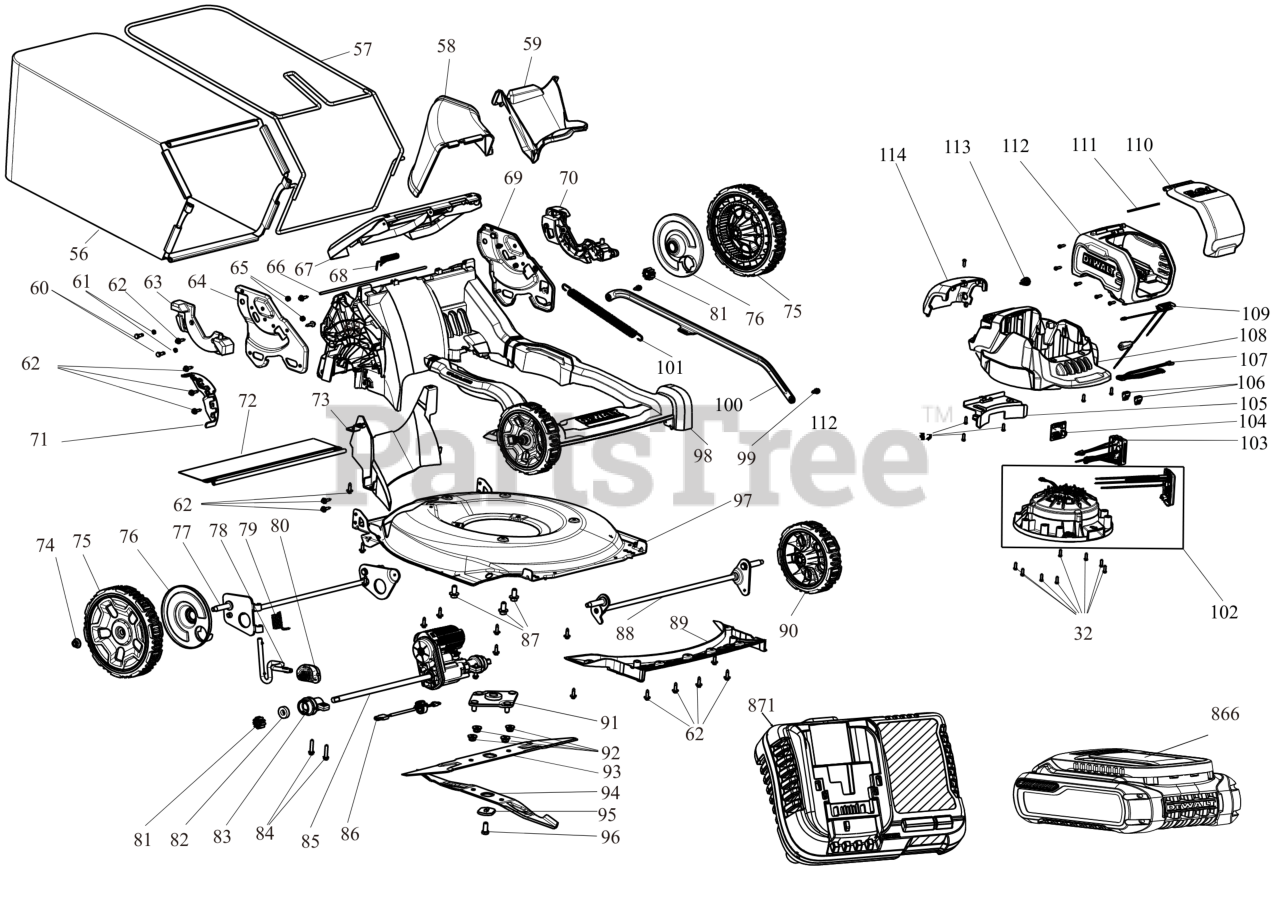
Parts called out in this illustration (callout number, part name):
1	BUTTON
2	SPRING
3	SCREW
5	COVER
6	POTENTIOMETER SA
7	CONTROL
9	BUTTOM
10	HANDLE
11	WIRE HARNESS
12	SWITCH
13	WIRE HARNESS
15	SCREW M6X45-T30-THD FRM
16	SWITCHBOX
18	HOUSING SA
19	CATCH
21	SPRING TORSION
22	WIRE HARNESS
23	PADDLE
24	PADDLE
25	PIVOT
26	COVER
27	STRIP
28	SLEEVE
29	TUBE UPPER
31	TUBE LOWER
32	SCREW M4.55X16 T20-PLAS THD FRM
33	SLEEVE
35	WASHER
36	SCREW
39	SPRING
41	SPRING
42	SPRING
43	COVER
46	SPRING
49	HOLDER
50	HARNESS
51	COVER
52	BUTTON
53	COVER
55	CORE
56	GRASSBAG
57	FRAME
58	CHUTE
61	SPACER
62	SCREW 1/4-10 x .750
63	SUPPORT
64	BRACKET
65	LOCK-NUT
68	SPRING
69	BRACKET
70	SUPPORT
71	BRACKET
72	SHIELD
73	INSERT
74	FLANGE LOCK NUT
75	WHEEL SA
76	COVER LH
77	AXLE REAR
79	SPRING
82	BEARING
83	HOLDER
84	SCREW
85	TRANSMISSON SA
86	HARNESS
88	AXLE FRONT
90	WHEEL SA
91	PLATE
93	BLADE MOUNT
94	BLADE MOUNT
95	WASHER
97	CUTTER DECK
101	SPRING
102	MOTOR SA
103	MODULE
104	PCB SA
105	BAFFLE
106	CONNECTOR
107	HARNESS
108	MOTOR COVER
109	HARNESS
112	HOUSING
113	BUSHING
114	COVER
115	SA HANDLE PNL KIT RWD-YELLOW
116	LABEL
866	60V BATT FLEXVOLT 4AH/12AH DCB612
871	CHARGER
